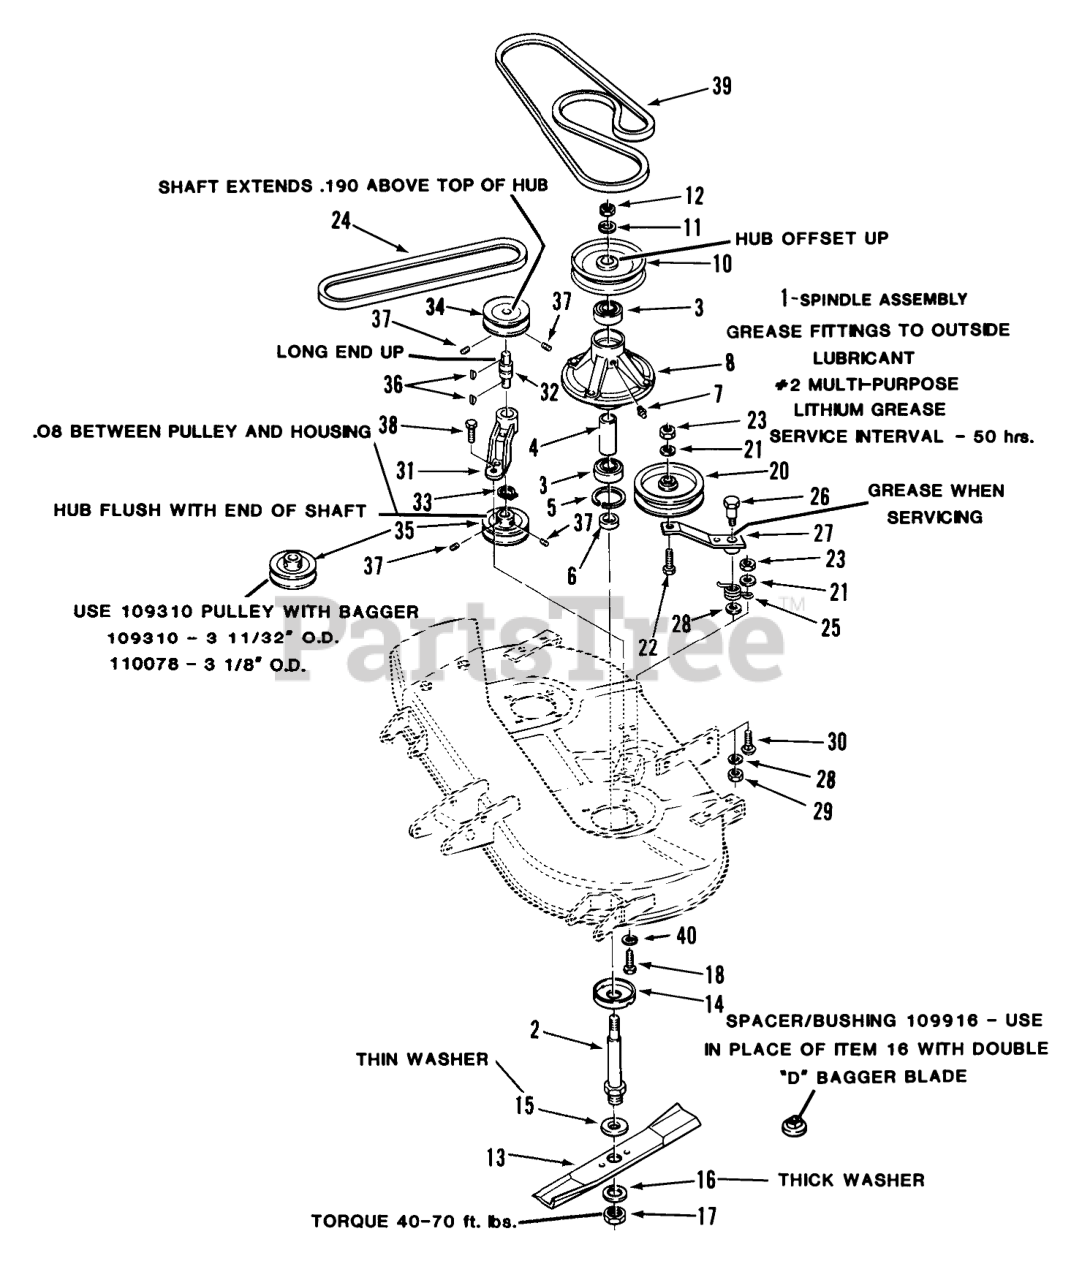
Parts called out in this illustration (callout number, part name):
1	Spindle Assembly,Metric Bearings (includes parts 2 to 8, 14)
2	SHAFT SPINDLE
3	BEARING-BALL
5	Ring-Snap
6	SPACER-BLADE
7	Fitting-Grease
8	HOUSING SPINDLE
10	PULLEY BLADE
11	Lockwasher
12	Jam Nut
13	ASSY BLADE KIT
14	CUP-SPINDLE
15	Washer
16	SpeciaI Washer
17	Nut-Jam
18	BOLT
20	Idler Pulley
21	Washer
22	Bolt
23	Nut
24	V-BELT
25	SPRING-TORSION
26	BOLT-SHOULDER
27	Idler Arm
28	WASHER
29	NUT-JAM(7/16-14)
30	Bolt
31	HOUSING DRIVE BRG R
32	BEARING-INT SHAFT
33	Snap Ring
34	PULLEY
35	PULLEY LOWER
36	KEY-WOODRUFF
37	Set Screw
38	Bolt
39	V-BELT
40	LOCKWASHER
